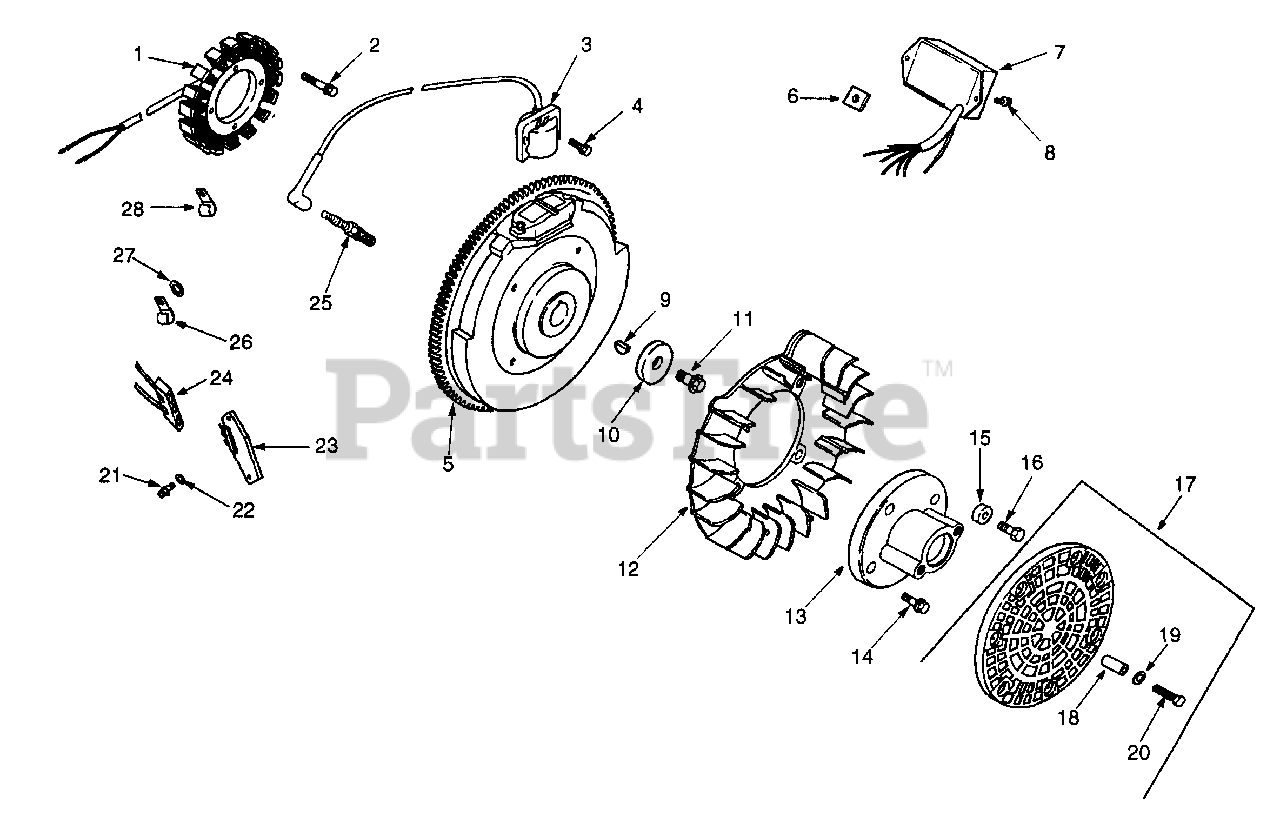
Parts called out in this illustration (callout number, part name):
1	Kit, 15 Amp Stator
2	Screw, Hex Cap M5 x 0.8 x 25
3	Module, Ignition
4	Screw, Hex Socket Hd. M5 x 0.8 x 25
5	Flywheel
6	Nut, Plastic
7	Module, Speed Advance
8	Screw, Phillips Hd. 11-16 x 1/2"
10	Washer, Plain 3/8"
11	Screw, Hex Flange M10 x 1.5 x 46
12	Fan
13	Adapter, Drive Shaft
14	Screw, Hex Flange M10 x 1.5 x 90
15	Spacer
16	Screw, Hex Flange M6 x 1.0 x 16
17	Kit,Grass Screen
19	Washer, Plain 3/16"
20	Screw, Hex Cap M4 x 0.7 x 25
21	Screw, Phillips Hd. 11-16 x 7/8"
22	Washer, Plain 3/16"
23	Rectifier-regulator 15 Amp
24	Connector (3 Contact)
25	Spark Plug
26	Clip, Cable
27	Washer, Plain 1/4"
